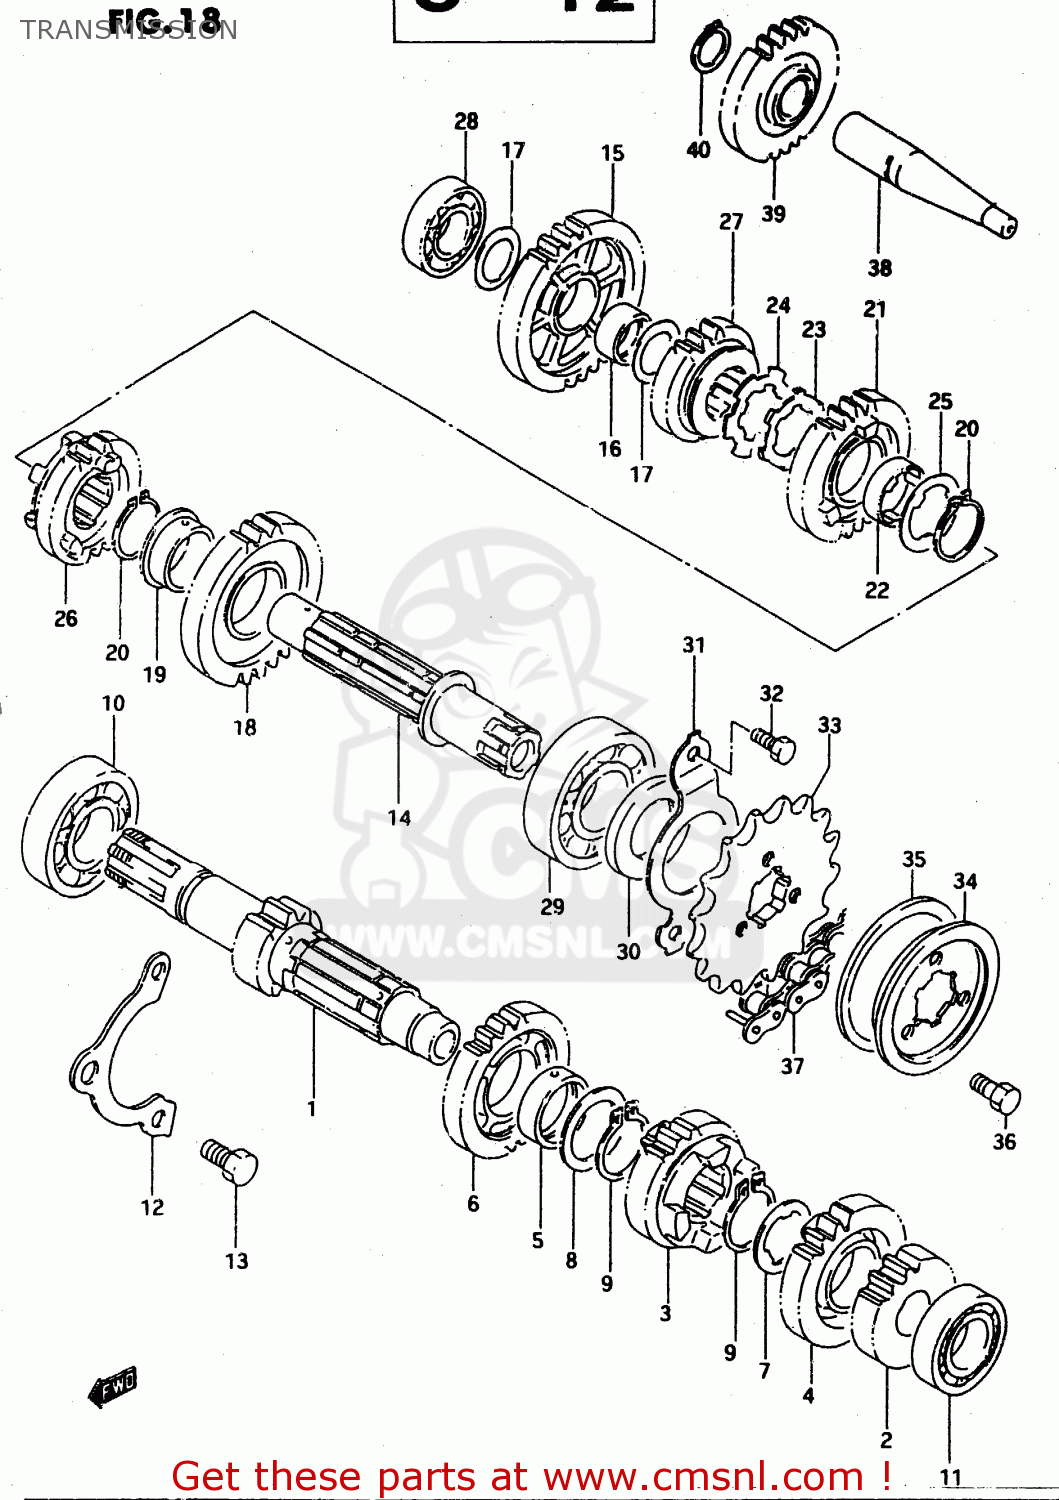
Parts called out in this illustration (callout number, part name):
1	SHAFT,COUNTER
2	GEAR,SECOND DRIVE
3	GEAR,3RD DRIVE
4	GEAR,FOURTH DRIVE
5	BUSHING 25X29X10
6	GEAR,5TH DRIVE
7	WASHER,LOCK
8	WASHER
9	RING,SNAP
10	BEARING
11	BEARING
12	RETAINER,CNTR SHAFT BEARING
13	BOLT
14	SHAFT,DRIVE
15	GEAR,1ST DRIVEN
16	BUSH(20X24X13)
17	WASHER
18	GEAR,2ND DRIVEN
19	BUSH
20	RING,SNAP
21	GEAR,3RD DRIVEN
22	BUSHING
23	WASHER
24	WASHER,LOCK
25	WASHER,LOCK
26	GEAR,FOURTH DRIVEN
27	GEAR,FIFTH DRIVEN
28	BEARING(20X42X12)
29	BEARING(25X62X17)
30	SEAL,OIL(25X45X5)
31	RETAINER,DRIVE SHAFT OIL SEAL
32	BOLT
33	SPROCKET,ENGINE(NT:16)
34	PLATE,ENGINE SPROCKET
35	DAMPER,ENGIN SPROCKET
36	BOLT(6X13)
37	CHAIN(DID520V,114L)
38	SHAFT,KICK STARTER IDLE
39	GEAR,KICK STARTER IDLE
40	CIRCLIP
